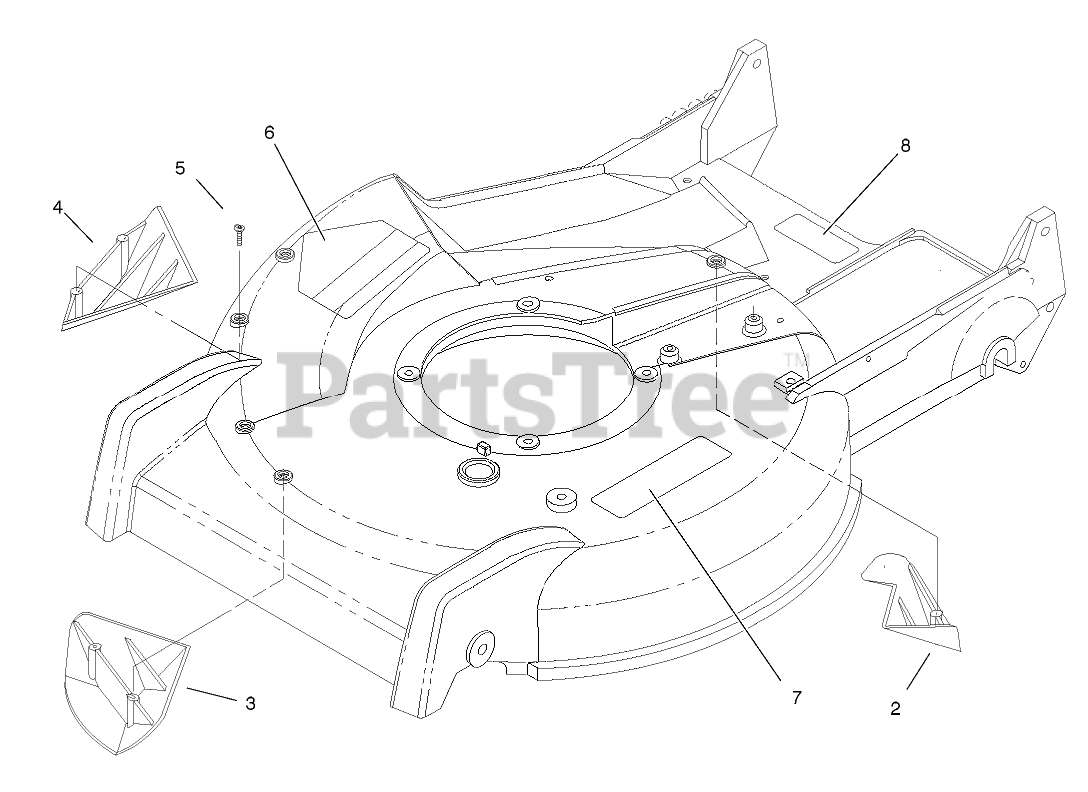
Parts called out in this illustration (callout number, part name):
2	KICKER-REAR
3	KICKER-FRONT
4	KICKER-RH
5	SCREW-PPH
6	DECAL-DANGER
7	DECAL-WARNING
8	DECAL-WARNING
